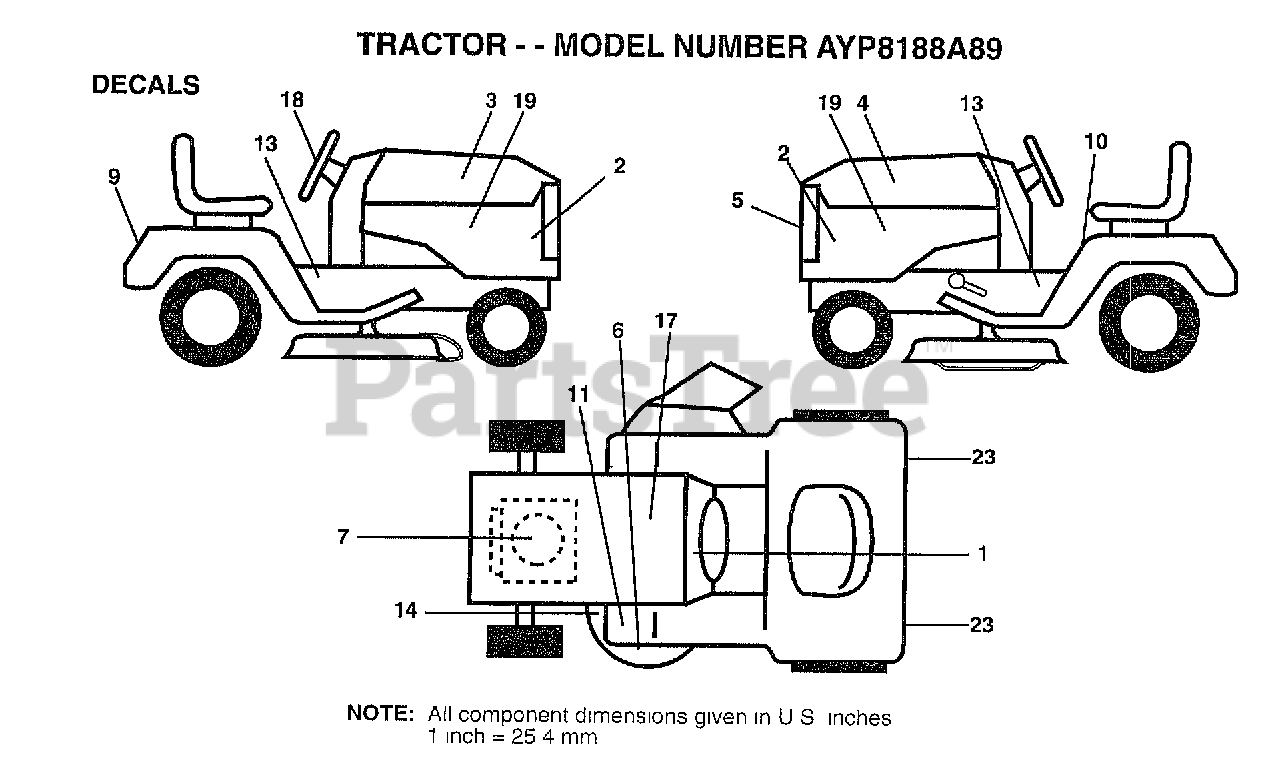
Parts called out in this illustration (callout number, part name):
1	"DECAL-OPER,GEAR D"
2	NAMEPLATE.HD.WIZA
3	DECAL.HD.RH.WIZRD
4	DECAL.HD.LH.WIZRD
5	DECAL.GRILLE.WIZ+
6	DECAL DECK WIZ +
7	DECAL, ENGINE
10	"DECAL DANGER,FEND"
13	DECAL CHASSIS
17	DECAL.BATRY.3-3908
18	DECAL INS STG WHL
19	DECAL PANEL SIDE
23	REFLECTOR-TAIL YT
